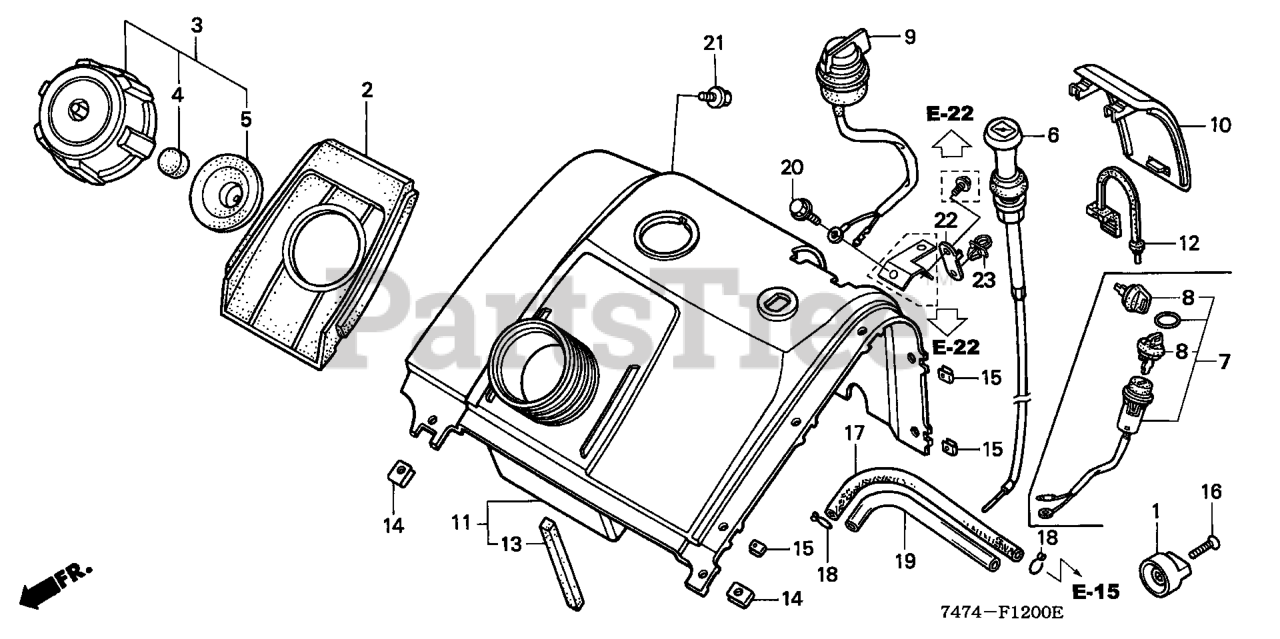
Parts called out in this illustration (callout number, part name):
1	LEVER, PETCOCK
2	RUBBER, FUEL GUIDE
3	CAP ASSY., FUEL TANK
4	SPONGE, FUEL CAP BREATHER
5	GASKET, FUEL CAP
6	CABLE, CHOKE
7	SWITCH ASSY., COMBINATION
8	KEY ASSY., COMBINATION SWITCH
8	KEY ASSY., COMBINATION SWITCH (RED)
10	COVER, PLUG *NH1* (BLACK)
11	COVER ASSY., RR. *NH1* (BLACK)
12	KNOB, PLUG COVER
13	RUBBER, SEAL
14	NUT, SPRING (6MM)
15	NUT, SPRING (5MM)
16	SCREW, OVAL (4X20)
17	BULK HOSE, FUEL (5.5X3000) (Honda Code 5338587). (5.5X150)
18	CLIP, TUBE (B10)
19	BULK HOSE, VINYL (11X13X3000) (11X13X210)
20	BOLT, FLANGE (6X10)
21	BOLT, FLANGE (6X16) Use from Engine SN 2056820.
22	STAY, WIRE CLIP
23	HOLDER, STOP SWITCH WIRE Use up to Engine SN 2056819.
